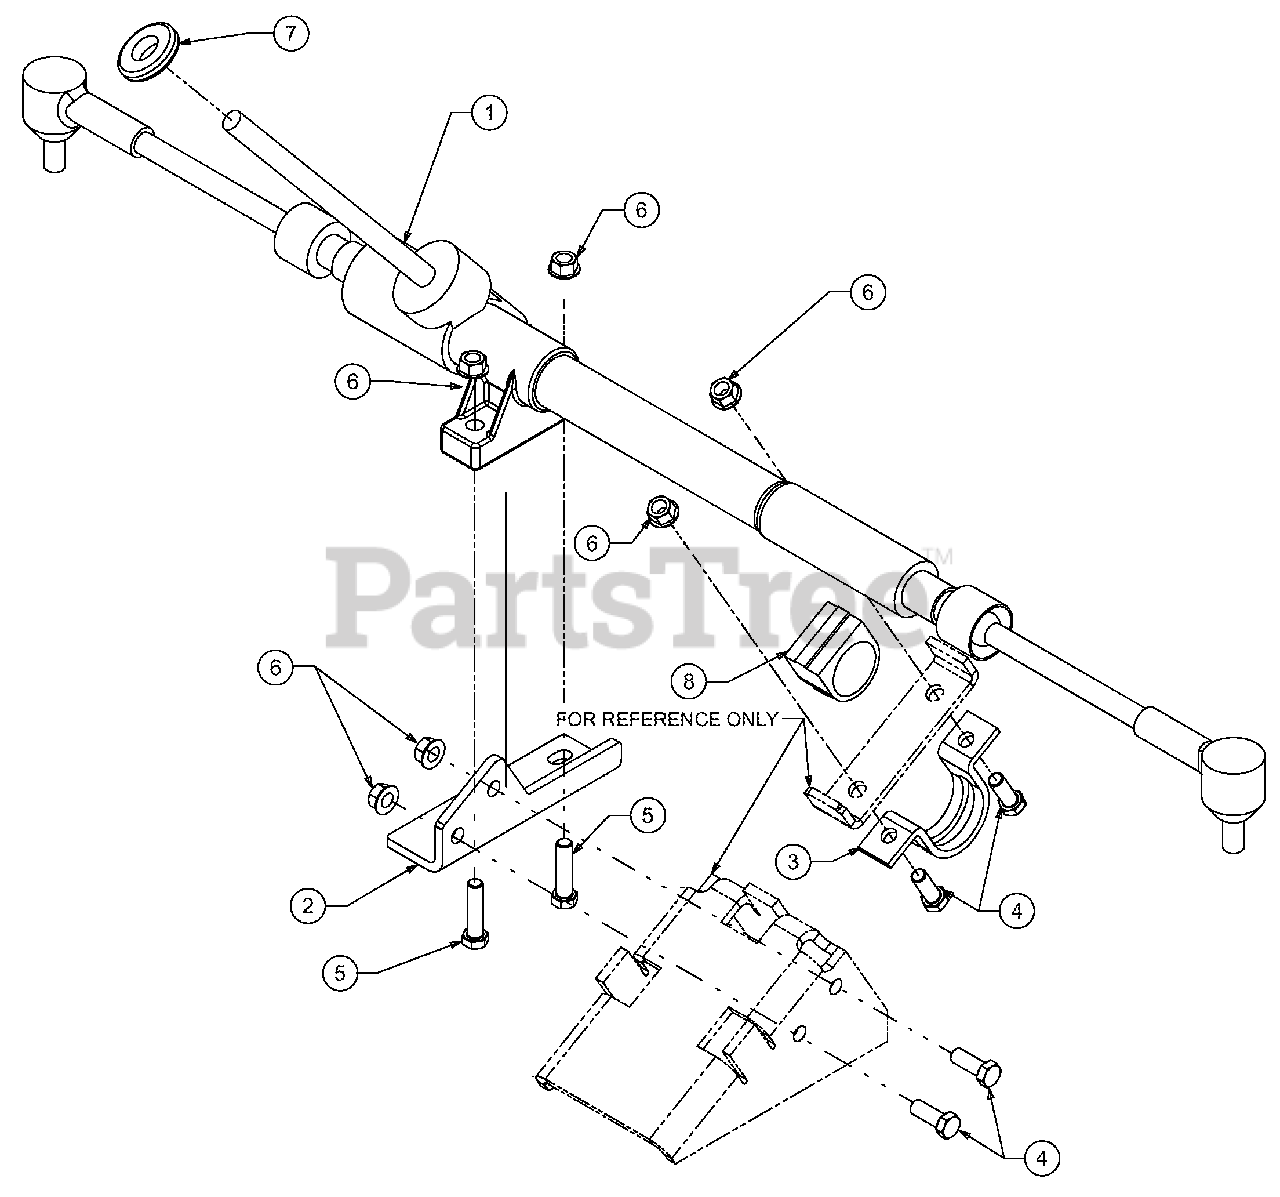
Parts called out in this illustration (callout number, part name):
1	Gear Assembly, Steering
4	Hex Screw, 3/8-16, 1.00, Gr5
5	Hex Screw, 3/8-16, 1.50, Gr5
6	Nut, Flange Lock, 3/8-16
7	Grommet, Steering Shaft
8	Bushing, Rubber
